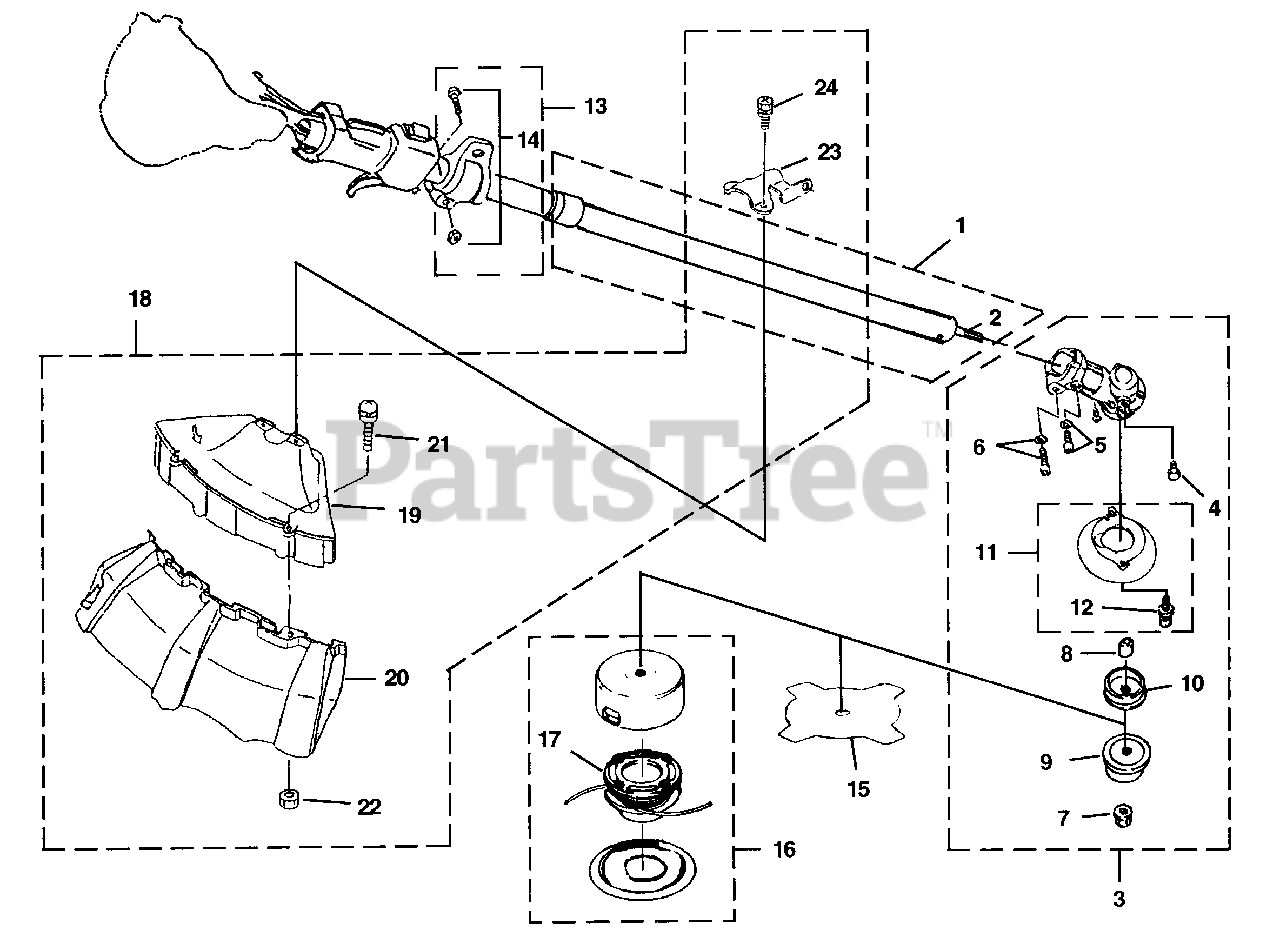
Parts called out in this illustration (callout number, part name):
1	DRIVESHAFT HOUSING
2	DRIVESHAFT
3	GEAR HEAD
4	BOLT-Grease
5	BOLT ASSEMBLY (M5 X 12 SW)
6	BOLT ASSEMBLY (M5 X 25 SW)
7	NUT
9	WASHER-Cupped
10	WASHER-Flange
11	GRASS GUARD
12	SCREW-Socket Hd (M5 x 12 W SW)
13	HANGER ASSEMBLY
14	SCREW AND NUT
15	BLADE CUTTER
16	STRINGHEAD ASSEMBLY (.095)
17	SPOOL & STRING (.095)
18	PROTECTOR ASSEMBLY
19	PROTECTOR COMPLETE
20	PROTECTOR COMPLETE
21	SCREW ASSEMBLY
23	CLAMP-Protector
24	BOLT ASSEMBLY
